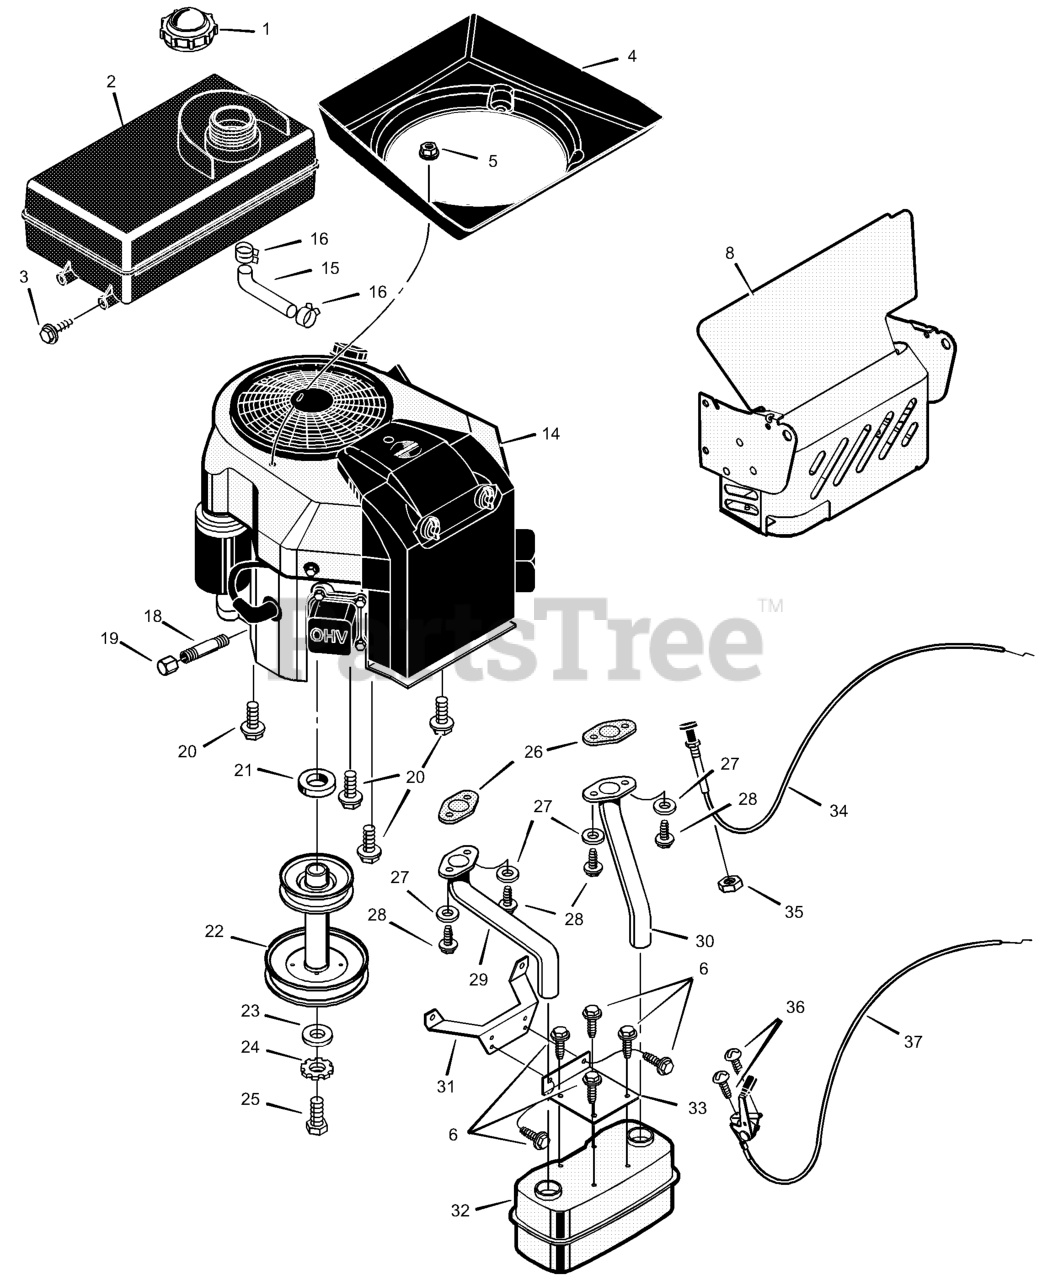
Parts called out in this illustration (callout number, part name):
1	Cap, Fuel
2	Tank, Fuel
4	Plenum, Air Intake
5	Nut
8	Shield, Heat
14	Engine *
15	Fuel Line (Must cut to length)
16	Clamp
18	Pipe, Oil Drain
19	Cap, Oil Drain
20	Bolt
22	STACK PULLEY ASSEMBLY
24	Lockwasher
27	Washer
28	Bolt
29	Tube, Right Exhaust
30	Tube, Left Exhaust
31	Bracket, Muffler Mount
32	Muffler
33	Bracket, Muffler
35	Nut
37	Control, Throttle
